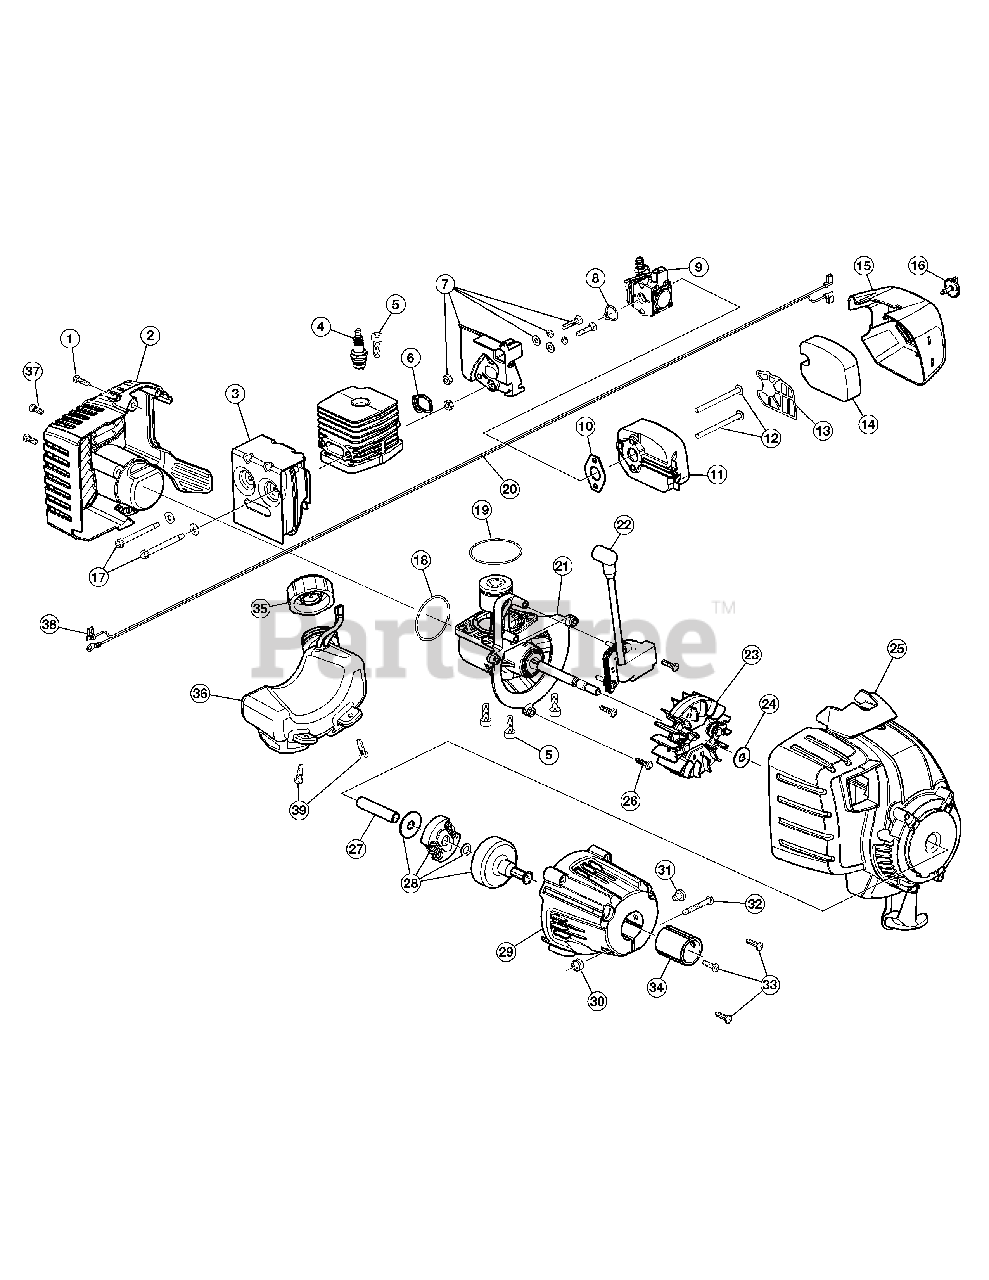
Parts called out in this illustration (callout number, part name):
2	Housing, Rear (Incl. 1, 18 & 37)
3	Muffler
4	Spark Plug
6	O-Ring
7	Insulator Assembly (Incl. 6 & 8)
8	O-Ring
9	Carburetor
10	Gasket
11	Air Cleaner Base
14	Filter
15	Air Cleaner Cover
17	Muffler Screw
18	O-Ring
19	O-Ring
20	Lead Wire
21	Shortblock (Incl. 4, 5, 19, 22, 23 & 24)
22	Module
23	Flywheel
24	Washer
25	Housing, Starter
26	Screw
27	Spacer
28	Clutch Assembly
29	Clutch Cover
32	Screw
34	Spacer, Rubber
35	Fuel Cap
36	Fuel Tank (Incl. 35 & 39)
37	Screw
39	Fuel Tank Screw
